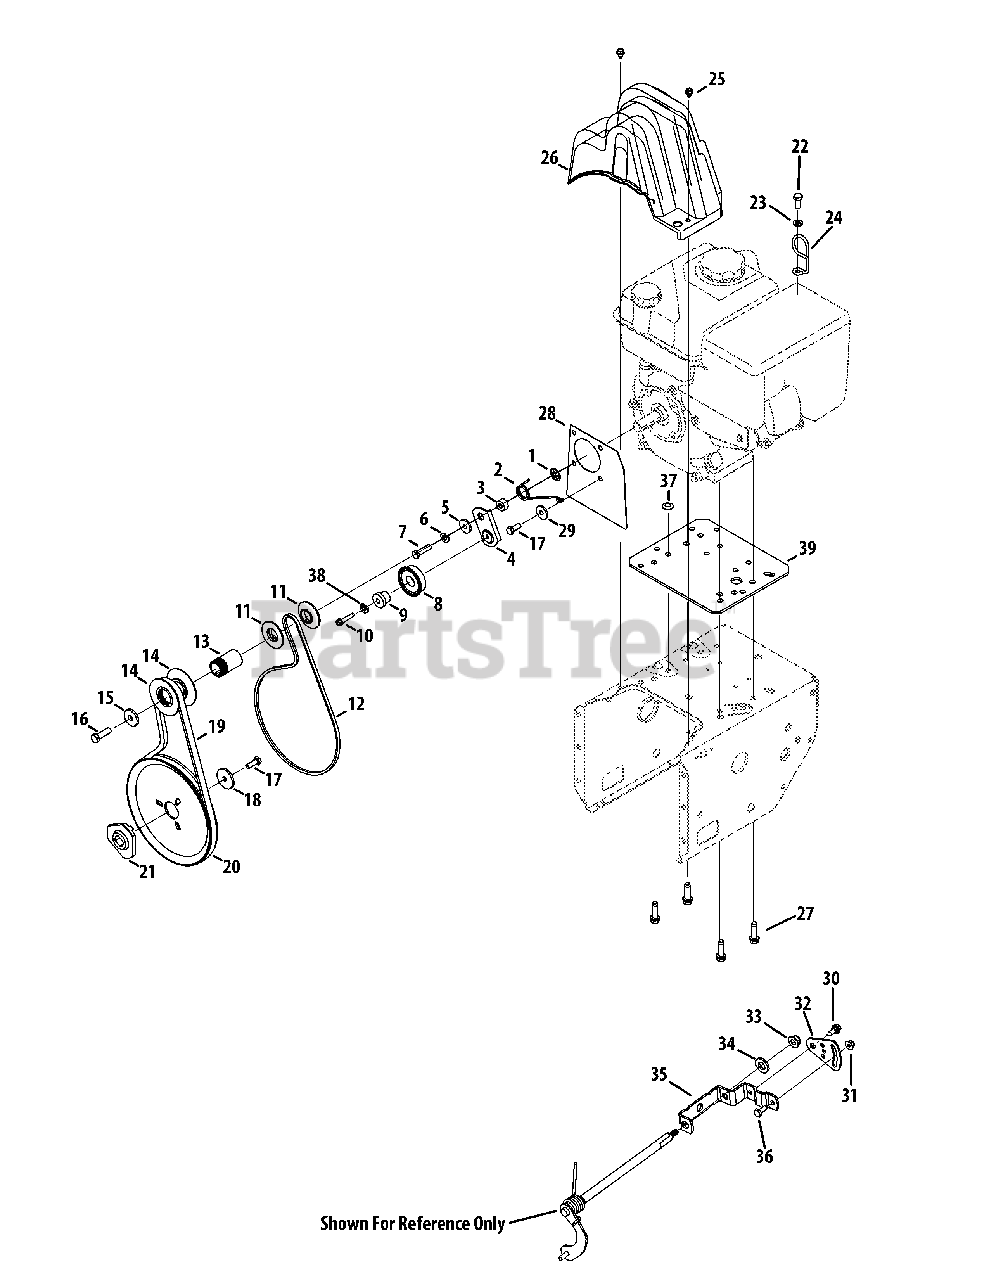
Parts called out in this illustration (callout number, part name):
1	Push-On Nut
2	Torsion Spring, .850 ID x .333
3	Spacer, .340 x .750 x .330
4	Idler Bracket
5	Shldr. Spacer, .3175 ID x .500 x .0975
6	Lock Washer, 5/16
7	Hex Screw, 5/16-24 x 1.25
8	Idler Pulley
9	Shoulder Spacer, .260 x .785 x .538
10	Hex Washer Screw, 1/4-20 x 1.250
11	Pulley Half, 3/8-V x 1.7160 OD
12	V-Belt
13	Spacer, .875 ID x 1.185 OD
14	Pulley Half, 4L-V x 2.600 OD
15	Flat Washer, .406 x 1.25 x .157
16	Hex Screw, 3/8-24 x 1.25
17	Hex Lock Screw, 5/16-24 x .875
18	Flat Washer, .34 x 1.50 x .150
19	Belt
20	Auger Pulley
21	Adapter Pulley
22	Hex Screw, M8-1.25 x 20
23	Flat Washer, .330 x .630 x .0635
24	Cable Control Wire
25	Hex Washer Screw, 1/4-20 x .375
26	Belt Cover
27	Hex Washer Screw, 3/8-16 x 1.250
28	Cover Plate
29	Shoulder Spacer
30	Shoulder Screw, .368 x .113 x 1/4-20
31	Flange Lock Nut, 1/4-20
32	Speed Selector Pivot Bracket
33	Flange Lock Nut, 5/16-18
34	Flat Washer, .469 x .875 x .105
35	Speed Selector Shift Bracket
36	Hex Screw, 1/4-20 x .620
37	Plug, 3/8 ID
38	Lock Washer, 1/4
39	Engine Plate
